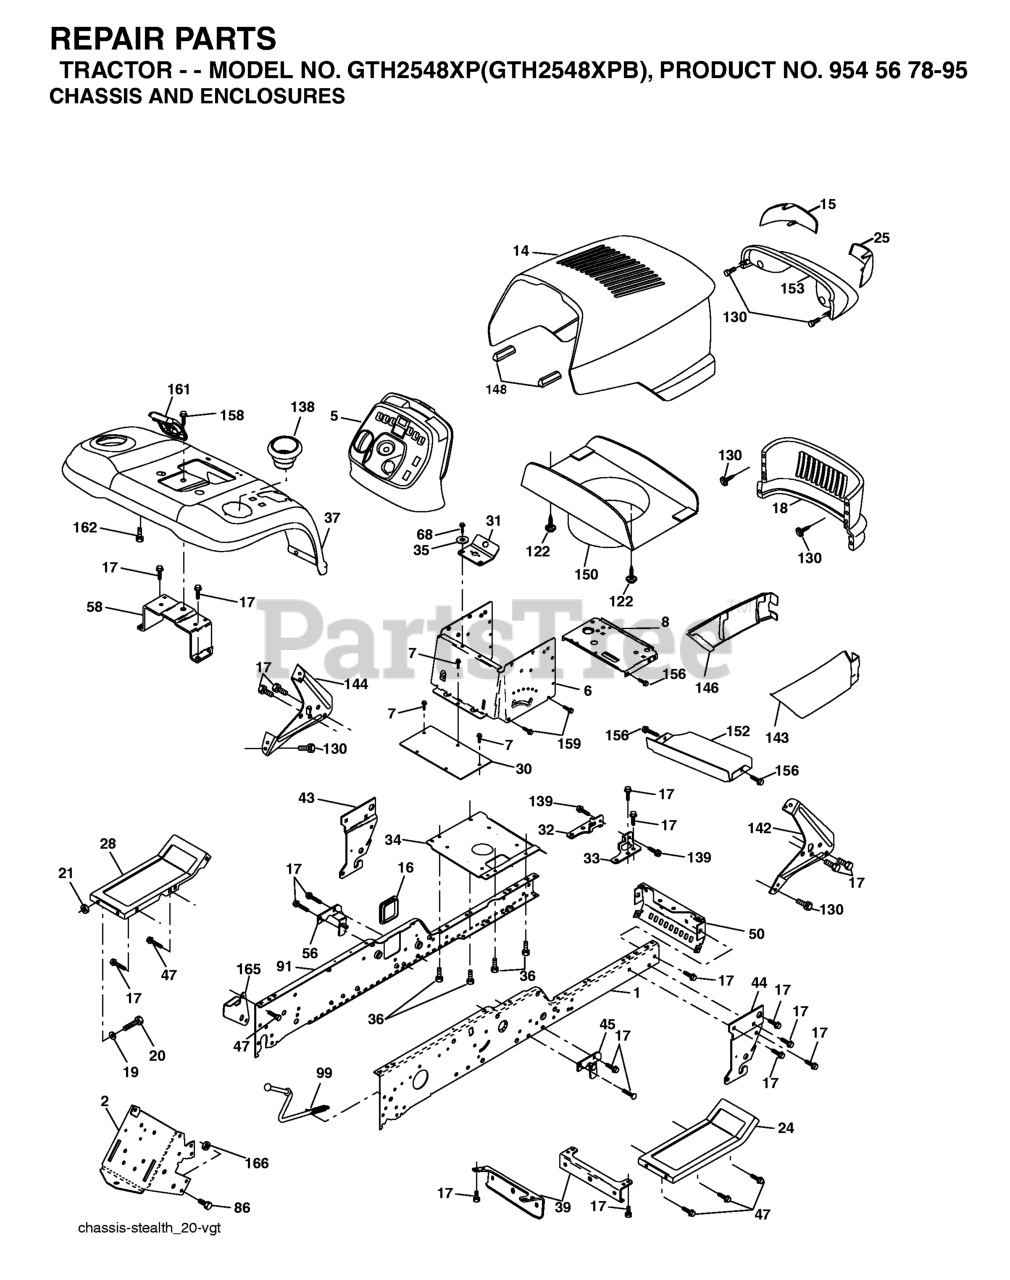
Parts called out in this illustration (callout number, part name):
1	KIT.RAIL.CHASS.RH.GT
2	DRAWBAR, GT
5	DASH, PLASTIC
6	DASH VGT, LOWER
7	SCREW
8	SUPPORT, BATTERY
14	HOOD ASM.
15	LENS LH
16	COVER ACCESS
17	SCREW 3/8-16X3/4
18	GRILLE
19	WASHER
21	NUT
24	FOOTREST PNT RH
25	LENS RH
28	FOOTREST PNT LH
30	SADDLE.HYDRO.95
31	BRACKET SUPT 1-PC VGT STEERING
34	PLATE ASM ENG CHASSIS
35	WASHER
36	SCREW 5/16"
37	FENDER, PNT
39	BRACKET AXLE, FRONT
43	FRONT SUSPENSION BRKT LH
44	FRONT SUSPENSION BRKT RH
45	BRACKET, ASM., SUSP CHASSIS RH
50	BRACKET, CHASSIS FRONT
56	BRACKET ASM., SUSP CHASSIS LH
58	BRACKET ASM., FENDER
68	Screw 5/16-18 x 1/2 Hex, Self Tapping 5/16-18 x 1/2
91	KIT.RAIL.CHASS.LH.GT
99	ROD ASM, BYPASS
122	SCREW.HEX.WS.HD.8-18 X 7/8
130	SCREW
138	CUPHOLDER
139	BOLT, SHOULDER 5/16-18
142	BRACKET DASH STEALTH(R)
143	SKIRT GRILLE RH
144	BRACKET DASH STEALTH LH
146	SKIRT GRILLE LH
148	EXTRUSION BUMPER (3 2) (2 2)
150	DUCT HEAT HOOD
152	BROWNING SHIELD
153	LIGHT ASM.
156	SCREW
158	SCREW 3/8-16X1/2
159	SCREW, 3/8-16X3/4
161	CONSOL.FUEL.WINDOW.BLACK
162	SCREW.HI-LO.CONSOLE
165	BRACKET SUPPORT TANK
166	Nut, Lock Hex 7/16 Unc
